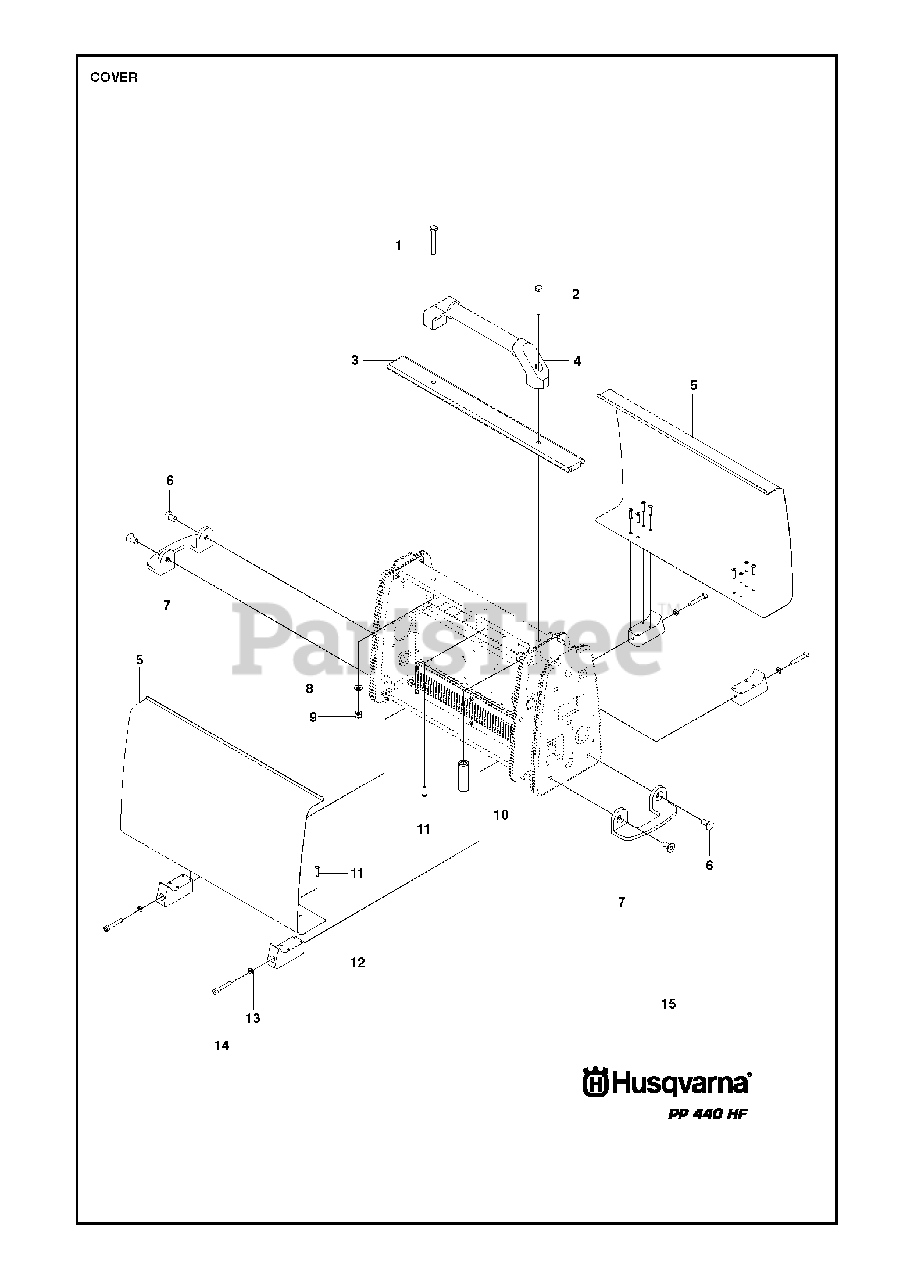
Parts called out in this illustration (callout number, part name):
1	SCREW IHSCM1 pcs on 200-280V
2	SCREW IHSCMOnly on 200-280V
8	WASHER
9	HEXAGON LOCKING NUT
10	SPACEROnly on 200-280V
